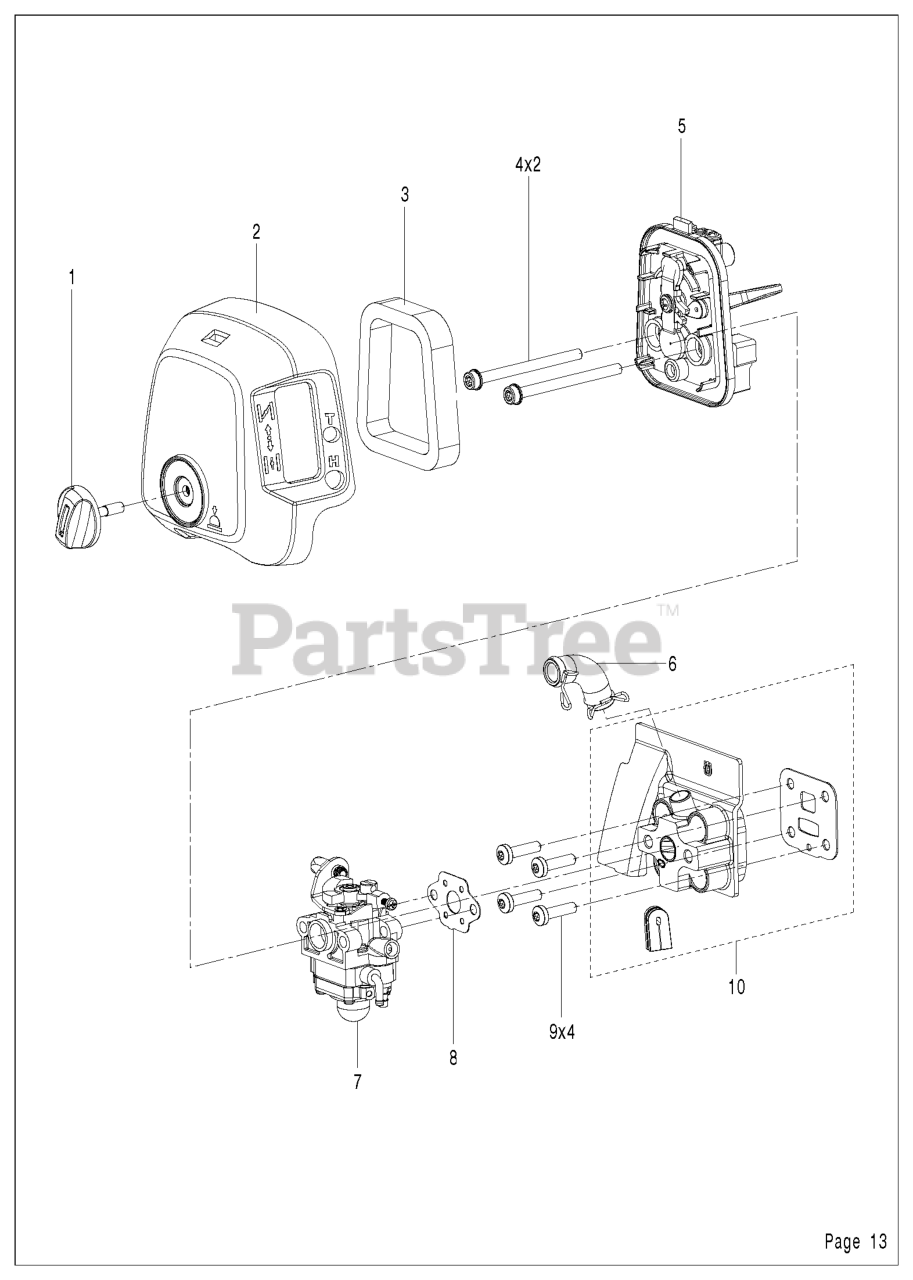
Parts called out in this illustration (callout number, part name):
2	SHAFT.ASM.CROSS.LIFT
3	LEVER.LIFT.HANDLE.GT
7	GRIP.HANDLE.LIFT.PVC.BLACK
10	SPRING.TORSION.LIFT.HANDLE
41	NUT, LIFT LINK 7/16-20
87	PIN.COTTER.7/16.BOW TI.
88	SPRING.LIFT.ASSIST
89	WASHER.CLEAR.ZINC
91	LINK.ASM.LIFT.54"TG
96	BUSHING SPHERICAL SUSP. FRONT
97	SCREW, 3/8-16X3/4
98	SUSPENSION WLDT FRONT DECK
114	NUT **
